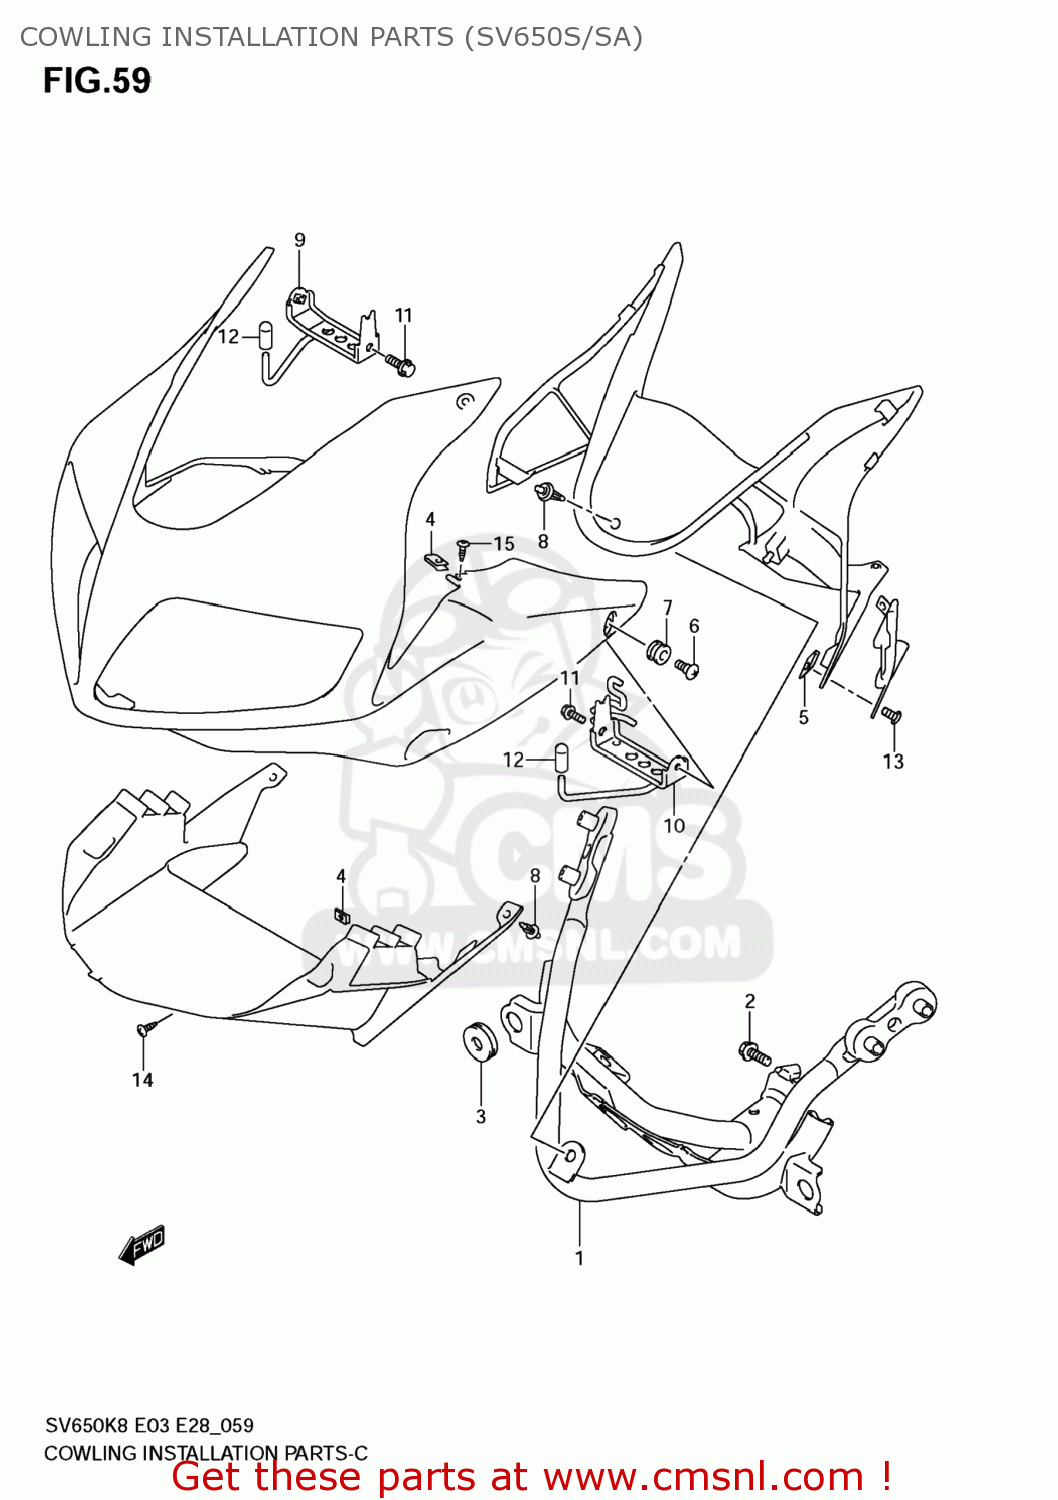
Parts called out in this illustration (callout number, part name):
1	BRACE,COWLING
2	BOLT
3	CUSHION
4	NUT,COWL
5	NUT
6	SCREW(6X20)
7	CUSHION
8	CLIP(BLACK)
9	BRACKET,COWLING FITTING,R
10	BRACKET,COWLING FITTING,L
11	BOLT
12	CAP
13	SCREW(5X16)
14	SCREW
15	SCREW(5X13)
